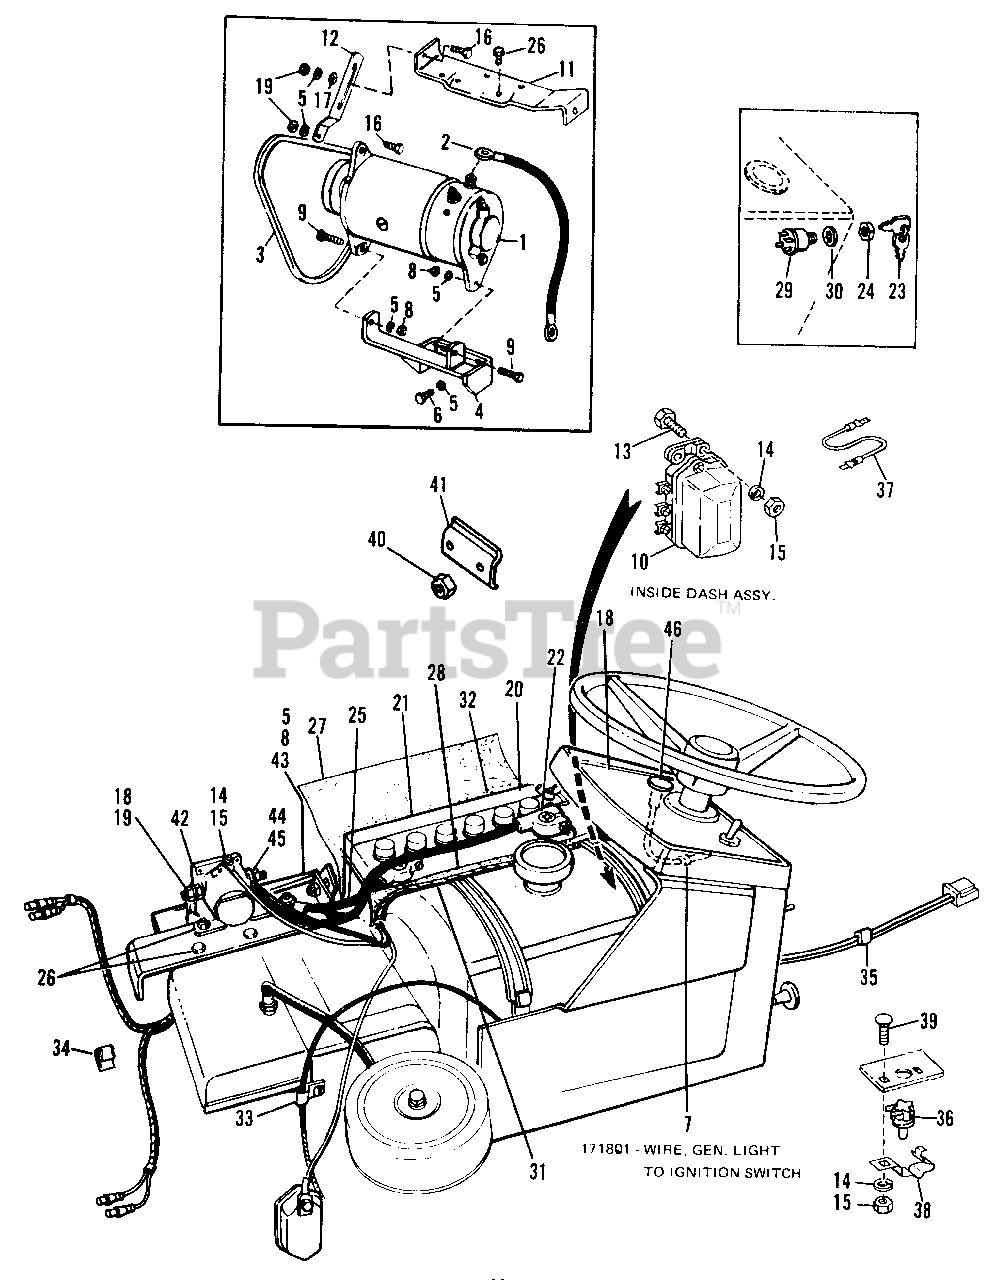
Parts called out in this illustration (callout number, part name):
1	Motor-Generator
2	Generator Start Cable
3	V-BELT, 39.12"
4	Support Assembly
5	Lockwasher, 5/16"
6	Hex Capscrew, 5/16"-18 x 3/4"
7	Wire Ignition to Gen. Light
8	Full Hex Nut, 5/16"-18
9	Hex Capscrew, 5/16"-18 x 1-1/4"
10	Voltage Regulator
12	Belt Tightener
13	Hex Capscrew, 1/4"-20 x 3/4"
14	Lockwasher, 1/4"
15	Full Hex Nut, 1/4"-20
16	Hex Capscrew, 5/16"-18 x 3/4"
17	Plain Washer, 5/16"
18	Circuit Breaker
19	Full Hex Nut, 5/16"-18
21	Film, Battery
22	Cable (Battery to Solenoid)
23	Key and Ring Assembly
24	Special Hex Nut
25	Cable (Battery to Ground)
26	Screw Hex Thread Forming, 1/4"-20 x 1/2"
27	Battery Insulation
28	Fuel Tank Insulation
29	Starter Switch w/Keys
30	Lockwasher Int., 9/16"
31	Harness Assembly
34	Speed Clip
37	Wire Assembly
38	Spring Clip
39	Carriage Bolt, 1/4"-20 x 3/4"
40	Elastic Stop Nut
41	Battery Clamp
43	Screw Hex Thread Forming, 1/4"-20 x 1/2"
44	Full Hex Nut, No. 10-32
45	Lockwasher, ext. No. 10
46	Indicator Lamp Assembly
